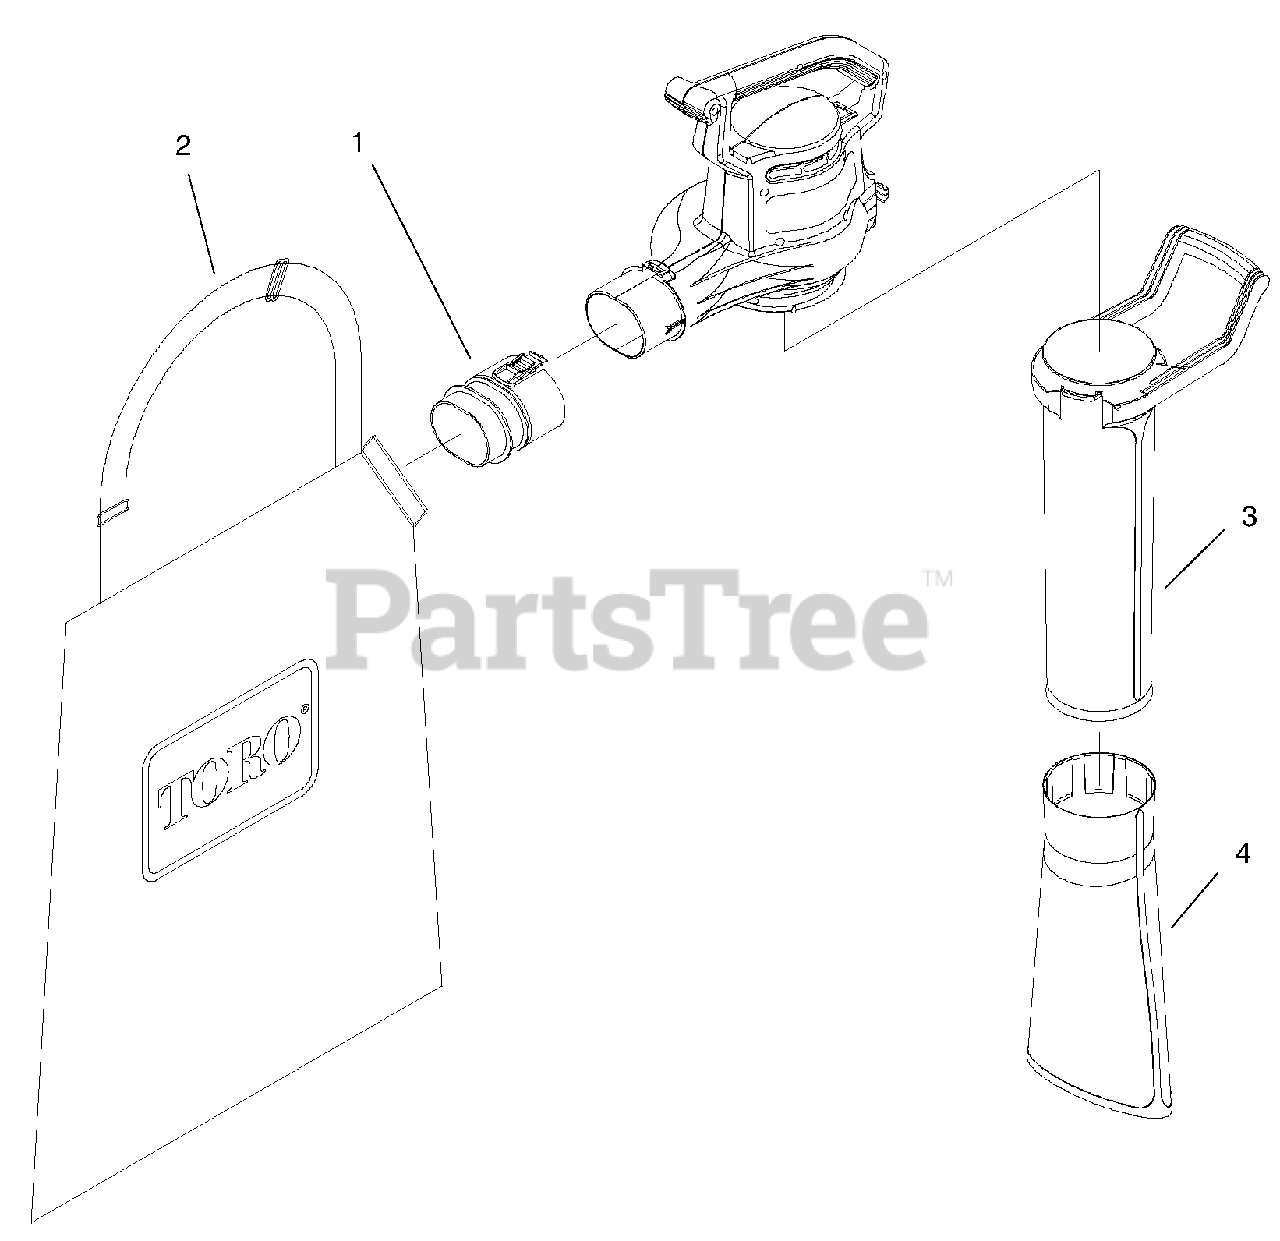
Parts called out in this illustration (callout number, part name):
1	Tube-Bag Inlet
2	Bag
3	Tube-Vac
4	Tube-Vac
